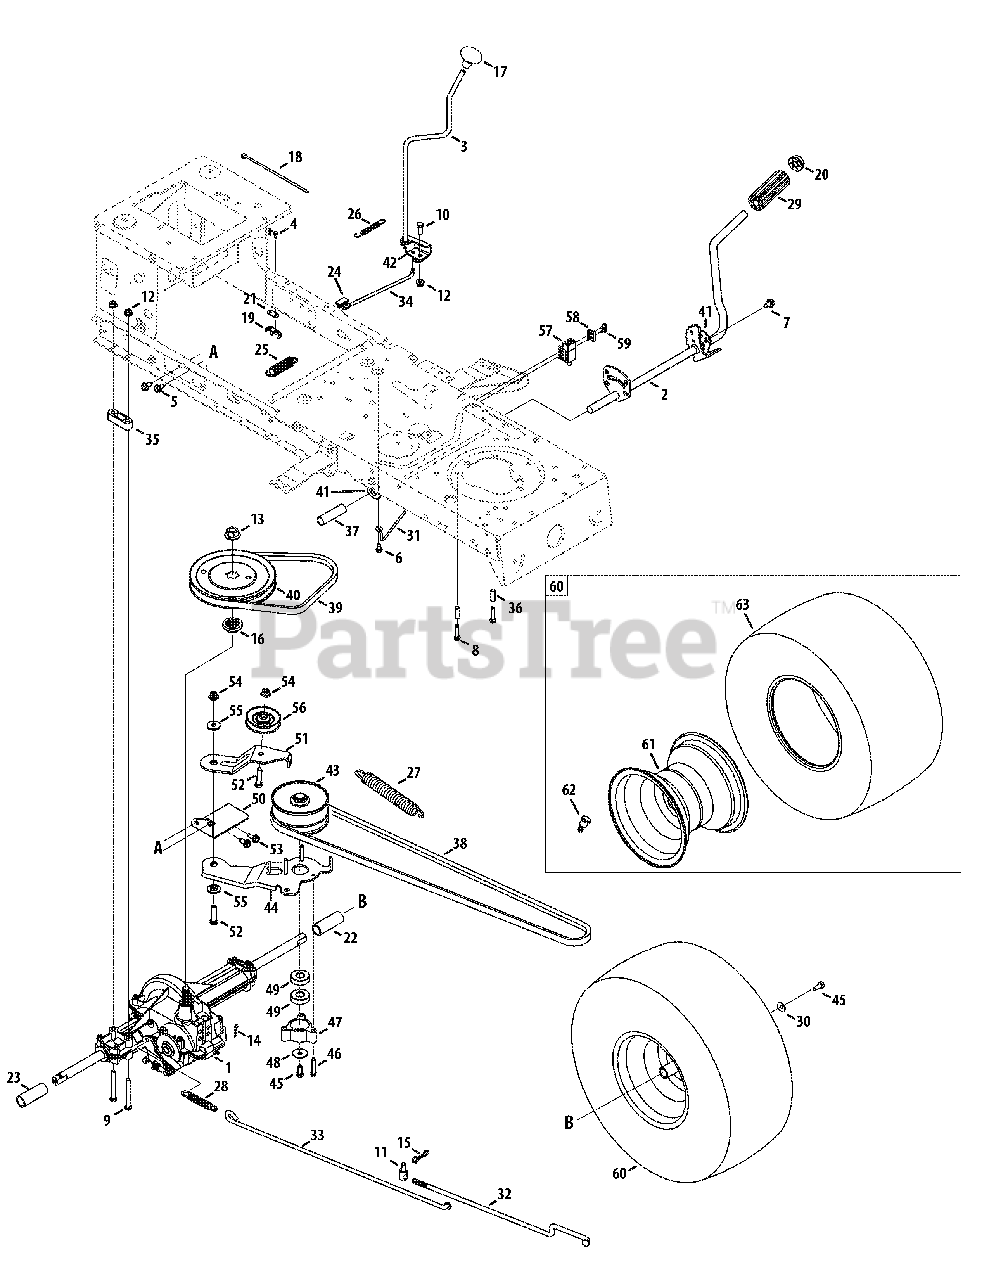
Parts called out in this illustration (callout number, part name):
1	Transmission Drive Assembly
2	Pedal Assembly
3	Shaft Lever Assembly
4	Screw, 8-18, 0.500
5	Screw, 5/16-18 x .750
6	Screw, 1/4-20 x 0.500
7	Screw, 5/16-18 x 0.625
8	Screw, 1/4-20 x 1.250
9	Hex Screw, 5/16-18 x .625
10	Hex Screw, 5/16-18 x .75
11	Ferrule, 3/8-24 X .375 DIA.
12	Flange Lock Nut, 5/16-18
13	Flange Nut, 9/16-18
14	Cotter Pin INT- .125 DIA
15	Bow-Tie Cotter Pin
16	Pulley Hub, 5/8 SPLINE
17	Shift Knob
18	Cable Tie
19	Short Spring Switch
20	Push Cap, 5/8
21	Plate Insulator Nut
22	Sleeve, .758 x .821 x 3.3125
23	Sleeve, .758 x .821 x 2.4375
24	Shift Bearing Plate
25	Spring Extension, .80 OD x 3.28 LG
26	Spring Extension, .38 OD x 3.25 LG
27	Spring Extension, .94 OD x 6.74 LG
28	Spring Extension, .59 OD x 4.00 LG
29	Foot Pad, 4.0 LONG
30	Bell Washer, .340 x .872 x .060
31	Belt Keeper Rod
32	Variable Speed Control Rod
33	Brake Rod
34	Shift Rod, 46"
35	Spacer, T-Axle
36	Spacer, .260 x .375 x 1.030 LG
37	Spacer, .640 ID x .76 OD x 2.63
38	V Belt, 5L, 70.90 POLY
39	V Belt, 5L, 33.8 POLY
40	Trans. Pulley
41	Pedal Support Bracket
42	Shaft Adjust Bracket
43	Variable Speed Pulley Assembly
44	Bracket Assembly
45	Hex Screw, 5/16-24 x .750
46	Screw, 1/4-20 x 1.500
47	Bearing Cup
48	Flat Washer, .330 x 1.25 x .06, HT
49	Ball Bearing, 17 x 40 x 12
50	Transmission Bracket Assembly
51	Idler Bracket Assembly
52	Hex Screw, 3/8-16 x 1.75
53	Screw, 5/16-18 x 0.750
54	Flange Lock Nut, 3/8-16
55	Shoulder Spacer, .625 ID x .169
56	Idler Pulley
57	Switch Interlock
58	Plate Switch
59	Shoulder Screw, #10-32 x .500
60	Wheel Assembly, 18 x 6.5
61	Rim Assembly
62	Valve Stem
63	Tire, 18 x 6.5 x 8 Sq. Sh.
